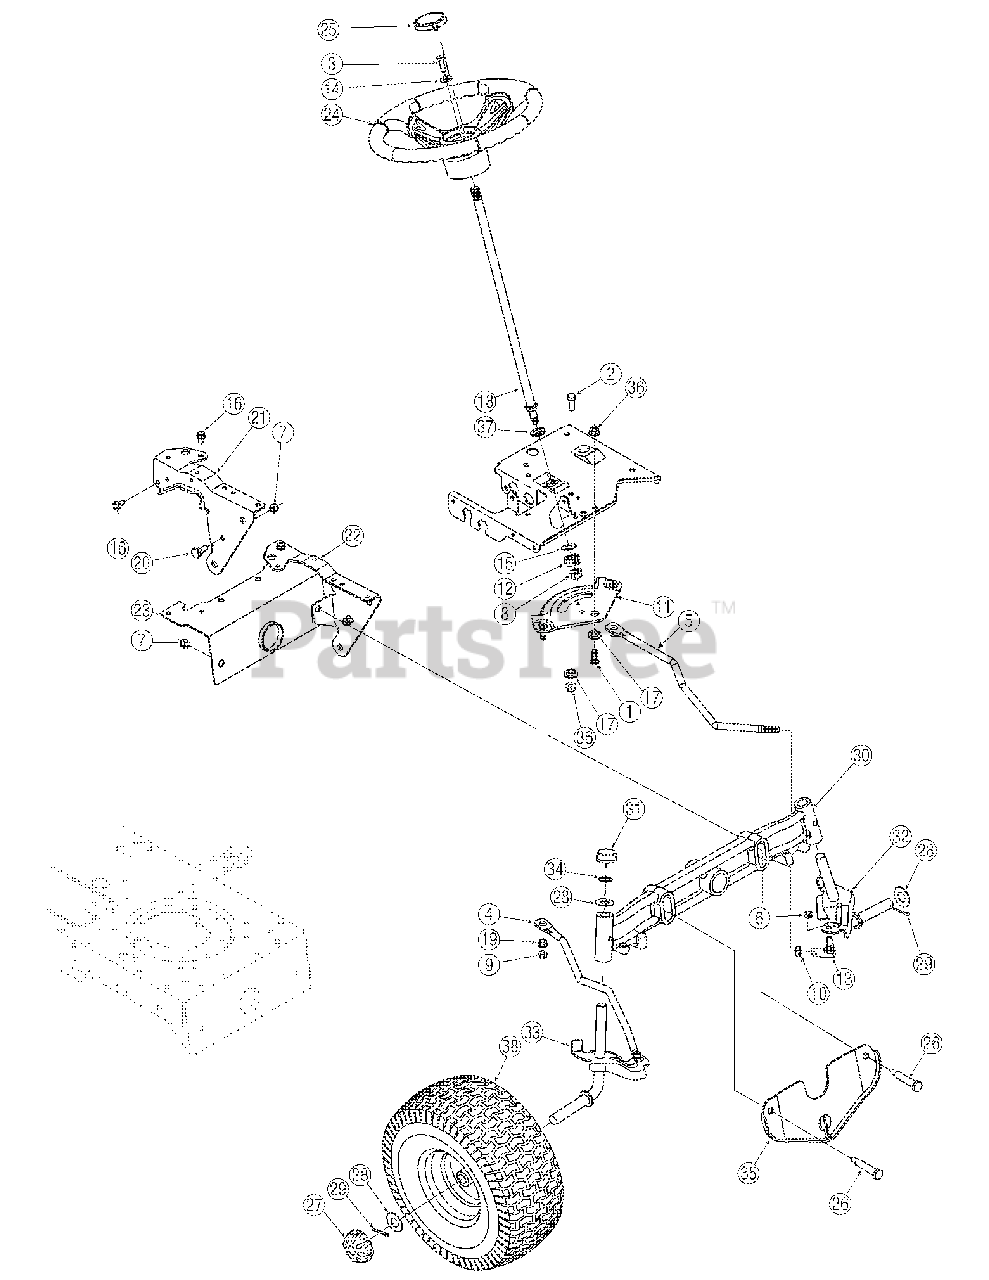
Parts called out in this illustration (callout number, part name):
1	Hex Screw, 3/8-16, 1.00, Gr5
2	Hex Screw, 3/8-16, 1.00, Gr5
3	Hex Screw, 5/16-18, 1.00, Gr5
4	Link, Drag, RH
5	Link, Drag, LH
6	Nut, Hex Lock, 3/8-24
7	Nut, Flange Lock, 3/8-16, Grf
8	Nut, Flange Lock, 7/16-20
9	Nut, Flange Lock, 5/16-18, Gr5
10	Nut, Jam, 7/16-20, Gr2
11	Gear, Steering, 11/90 Ratio
12	Gear, Pinion, Steering
13	Ball Joint, 7/16-20, Lock
14	Washer, Flat, .406 x .875 x .105
15	Washer, Flat, .51 x 1.12 x .06
16	Screw, 5/16-18, 0.750
17	Spacer, Shoulder, .38 x 1.00 x 31
18	Shaft, Steering, .625 OD x 24.25
19	Plastic Bushing .380 ID
20	Screw, Shoulder, .498 x .340
24	Steering Wheel
25	Steering Wheel Cap
26	Shoulder Screw, .5 x 2.380, 3/8-16
27	Deluxe Hub Cap
28	Flat Washer, .78 x 1.589 x .06
29	Cotter Pin, 5/32 x 1.25
30	Pivot Bar, Cast Iron
32	LH Axle Assembly, .750
33	RH Axle Assembly, .750
36	Flange Lock Nut, 3/8-16
37	Hex Flange Bearing
38	Wheel Assembly Complete, 15 x 6
38	Tire Only 15 x 6 x 6
